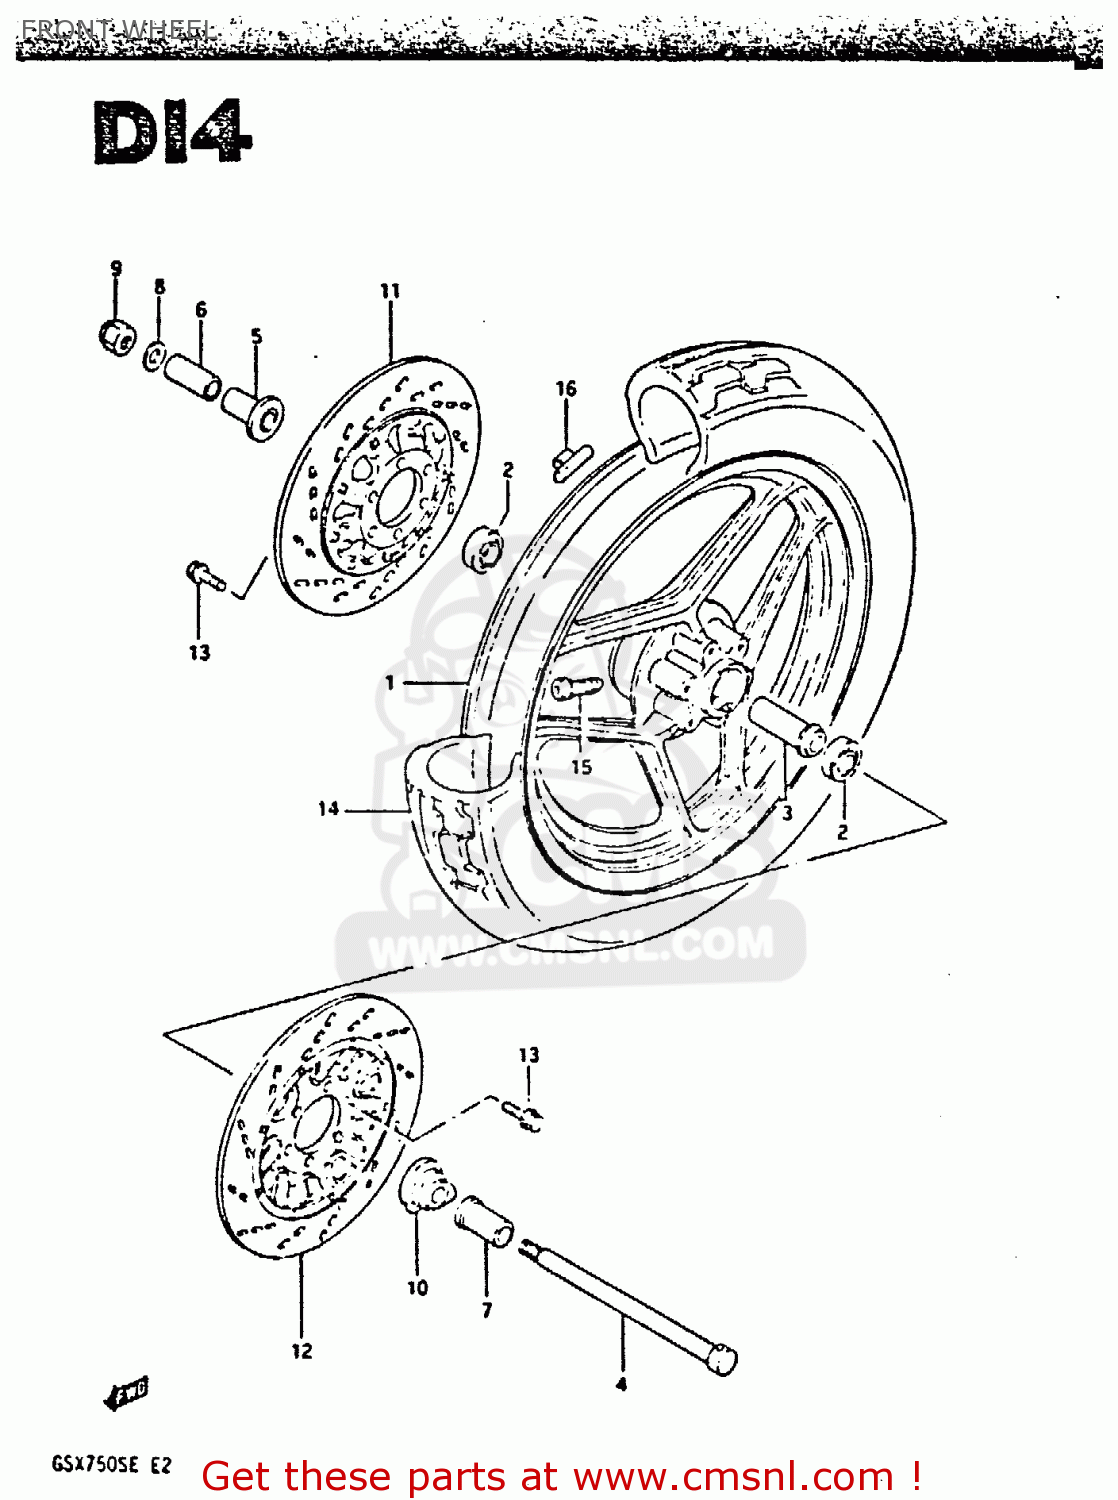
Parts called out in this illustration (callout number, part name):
1	WHEEL, FRONT (2.15*16) GOLD
2	BEARING
3	SPACER,FRONT HUB BEARING
4	AXLE,FR
5	SPACER,FR AXLE,R
6	SPACER,FR AXLE,R
7	SPACER,FR AXLE,L
8	WASHER
9	NUT
10	BOX ASSEMBLY,SPEEDOMETER GEAR
11	DISK, FRONT BRAKE RH
12	DISC,BRAKE
13	BOLT
14	TIRE, T/L FRONT (100/90-16)
15	VALVE,TIRE
16	BALANCER,WHEEL
